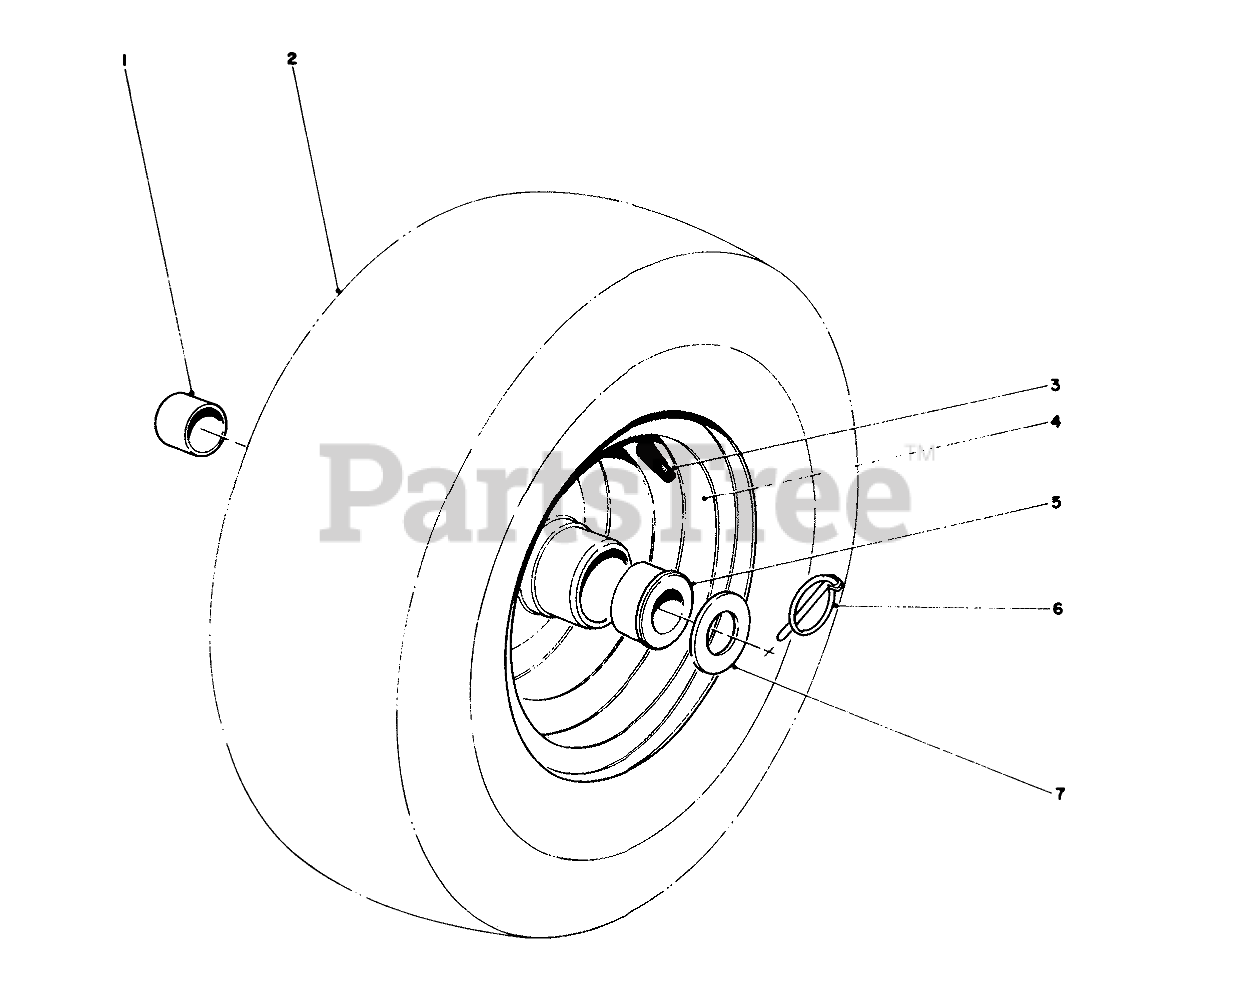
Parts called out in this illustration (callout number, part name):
1	.877ID X .750LG BSHG
2	Tire
3	STEM-VALVE
4	Wheel & Hub Assembly (Incl. Ref. #1 & 5)
5	BUSHING
6	PIN-LYNCH
7	WASHER-THRUST
